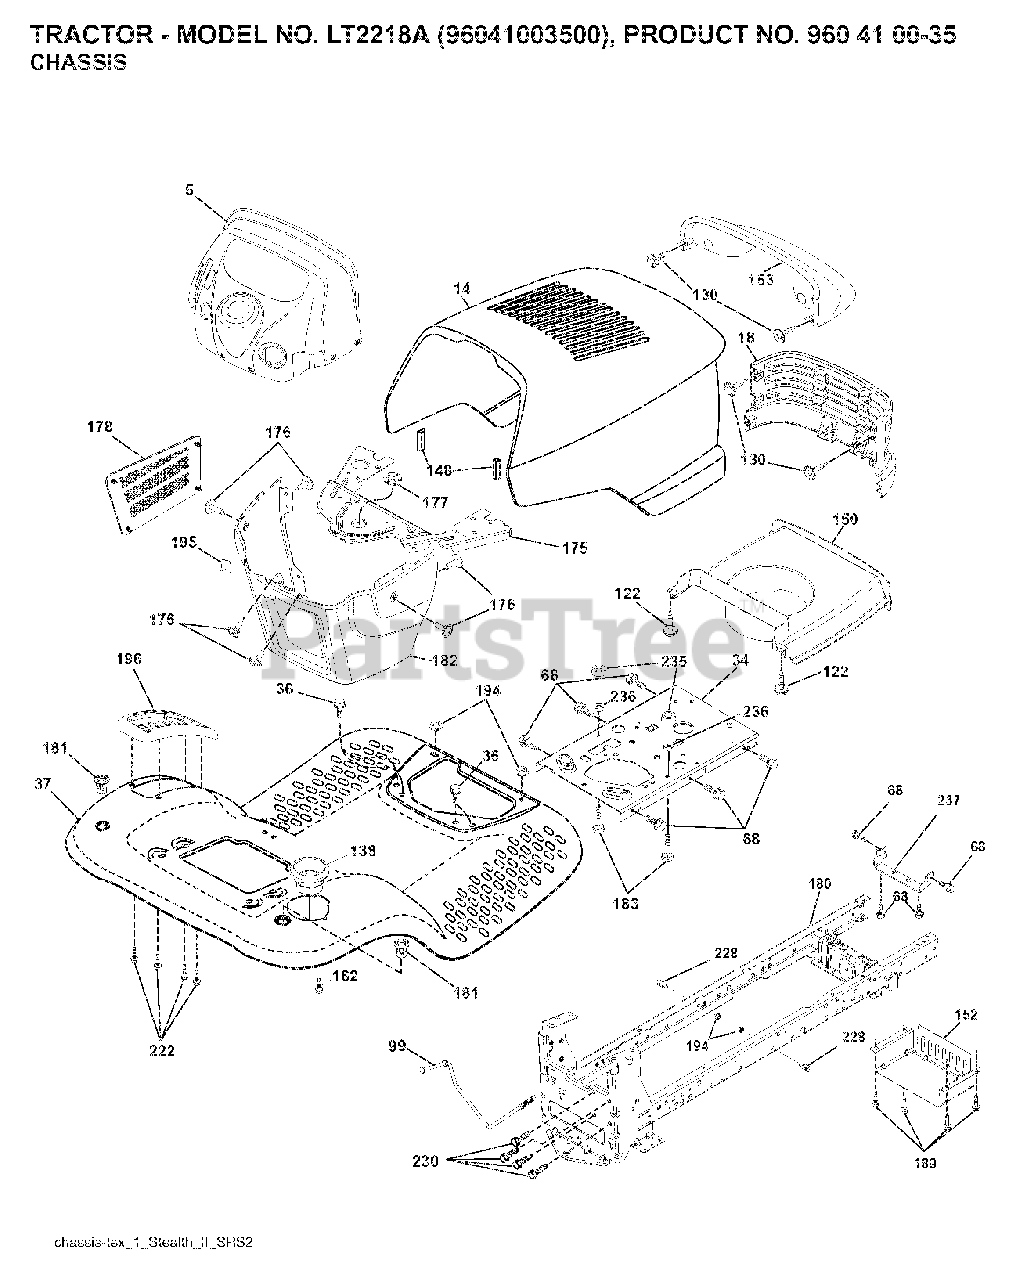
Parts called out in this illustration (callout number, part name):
34	PLATE.ENGINE.WELDED.CHASSIS
36	SCREW 5/16"
99	ROD.ASM.BYPASS.0510.HYDRO.LT
130	SCREW
138	CUPHOLDER.TL.TEX.BLACK
148	EXTRUSION BUMPER
150	DUCT HOOD
152	SHIELD BROWNING
162	SCREW.HI-LO.CONSOLE
175	CROSSMEMBER.
176	SCREW.#10-24X5/8.RN.QU
177	BUSHING,STEERING
178	CARGO.ASM.NET.DASH.LOWER
180	CHASSIS
181	FEND/FTRST.PCH.CPH.NFW
182	DASH.LOWER.
183	BOLT.5/16-18X1-1/4 FULL.THREAD
189	SCREW
194	NUT LOCK HEX FLANGE 5/16-18
195	PLUG.HOLE.DASH.LOWER.12V.BLK
196	CONSOLE.ASM.DECK.LIFT.TLT.BLAC
222	SCREW.1/4-20X5/8
228	STUD.FASTNER.W/ANTI-ROTATE
230	SHOULDER BOLT 5/16-18TT
235	SPACER FENDER
236	NUT.CENTERLOCK.5/16-
237	BRKT.HOOD/MUFF.STEALTH
